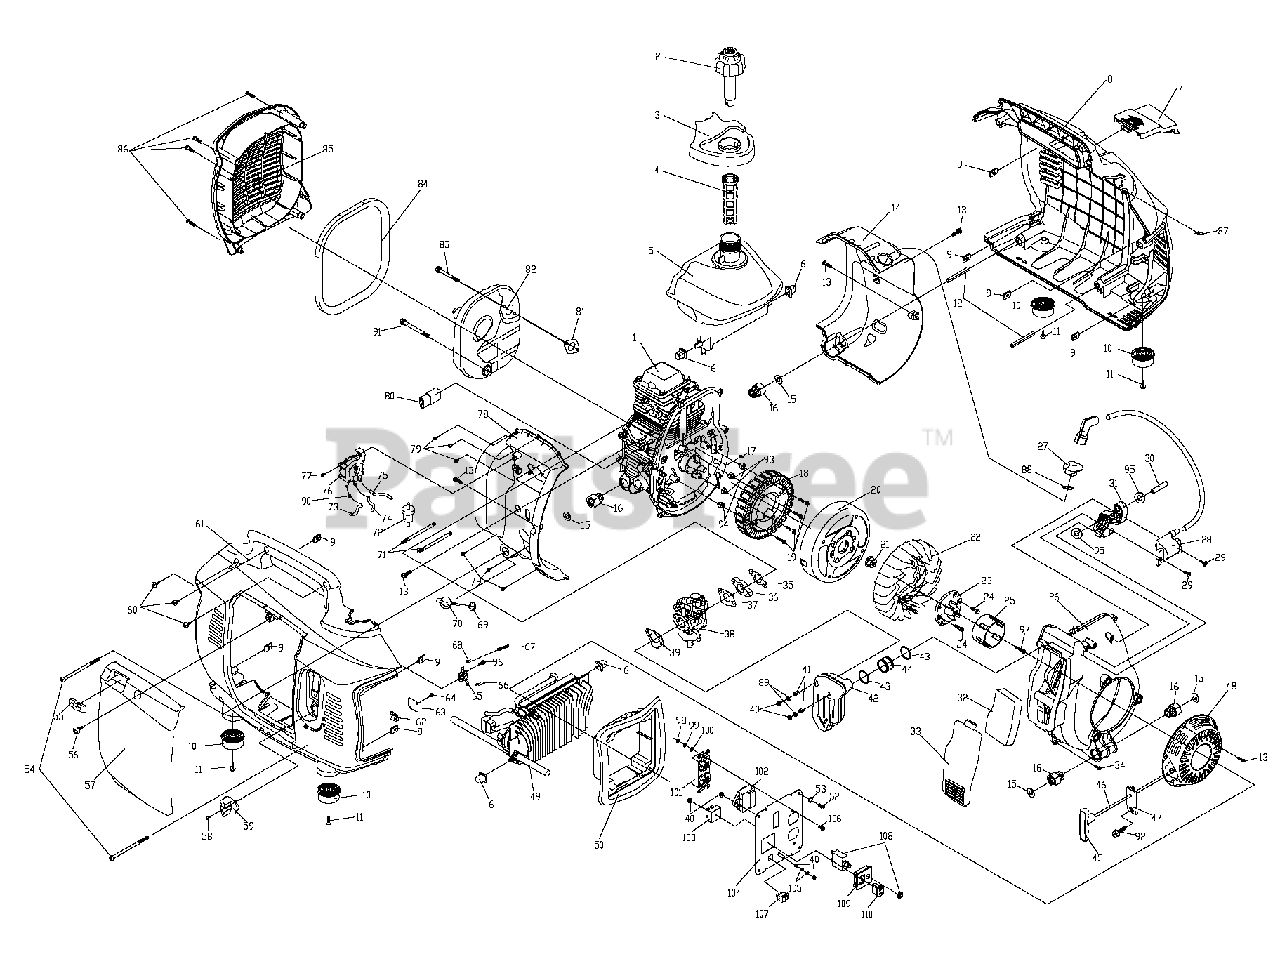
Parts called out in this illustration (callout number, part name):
72	FILTER, GAS
73	HOSE, FUEL PUMP
74	HOSE, FUEL PUMP AIR
75	HOSE, FUEL PUMP OIL INJECTION B
76	FUEL PUMP ASSY.
77	SCREW, PHILIPS, ST4.8X19
78	WRAPPER, ENGINE, UPPER
79	SCREW, PHILIPS, ST4.2X13
81	GASKET, MUFFLER
82	MUFFLER ASSY.
83	BOLT, HEX HEAD W/FLANGE, M6X60
84	SEAL, EXHAUST COVER
85	COVER, EXHAUST
86	SCREW, CROSS PAN HEAD, M5X20
87	CLIP, RETAINING, CHASSIS
88	O-RING, RUBBER
90	CLIP, HOSE, FUEL
91	BOLT, HEX HEAD W/FLANGE, M6X80
92	SCREW, PHILIPS W/WASHER, M5X12
93	PIN, GUIDE, A
94	PIN, GUIDE, B
95	WASHER/ GASKET, HOOK
96	SCREW, PHILIPS
97	BOLT, HEX WITH FLANGE
99	WASHER, LOCK, M4
100	WASHER, FLAT, M4
101	OUTLET, 120 VAC 20 AMP
102	IGNITION APPARATUS(W/LED INDICATOR)
103	DIODE, RECTIFIER
104	PANEL, FRONT
105	WASHER, STAR LOCK M6
106	SCREW M4X12
107	SWITCH, FLEXPOWER
108	BREAKER, DC CIRCUIT
109	HOLDER, DC COMPONENTS
110	RECEPTACLE, 12 VDC
